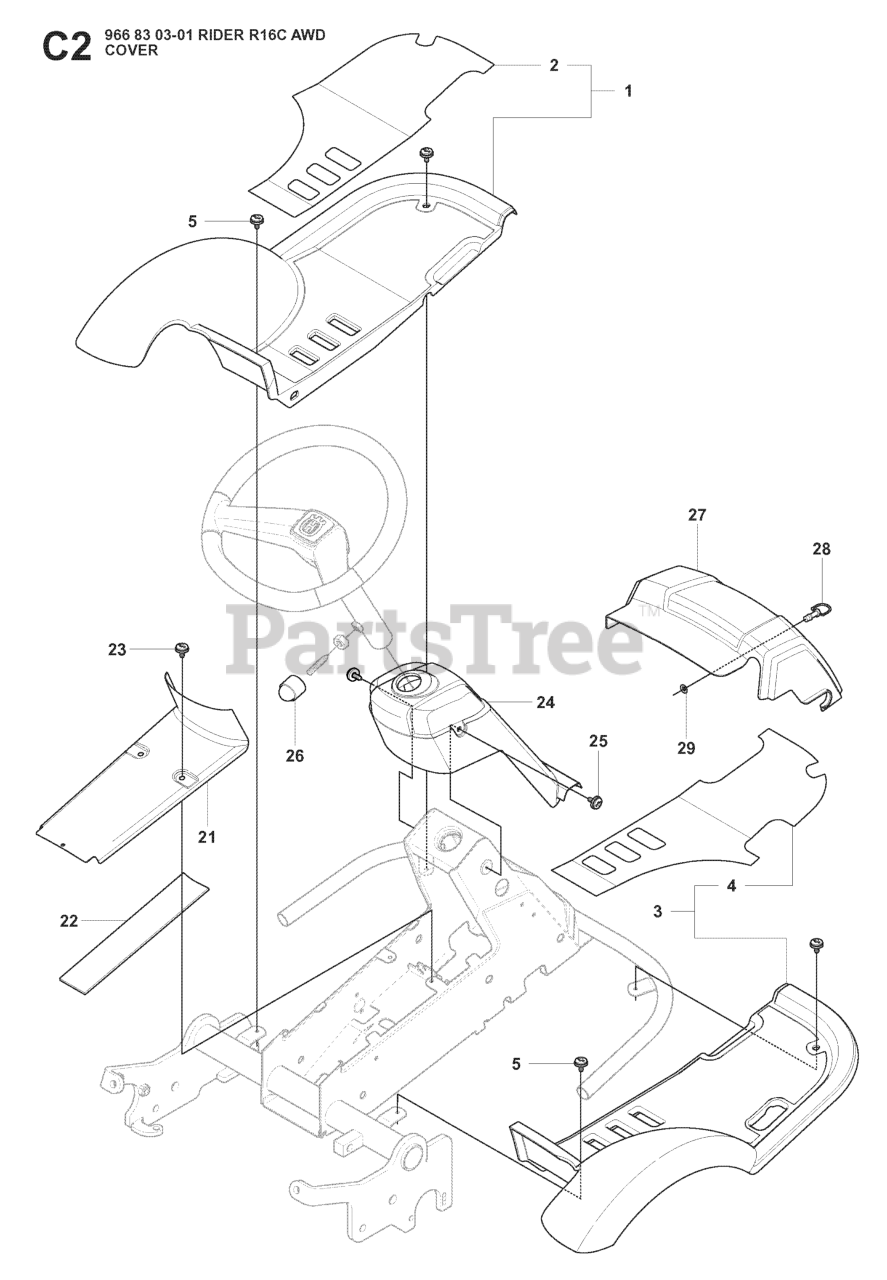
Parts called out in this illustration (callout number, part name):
1	FOOT PLATE
3	FOOT PLATE
26	PROTECTIVE COVER
28	BOLT
